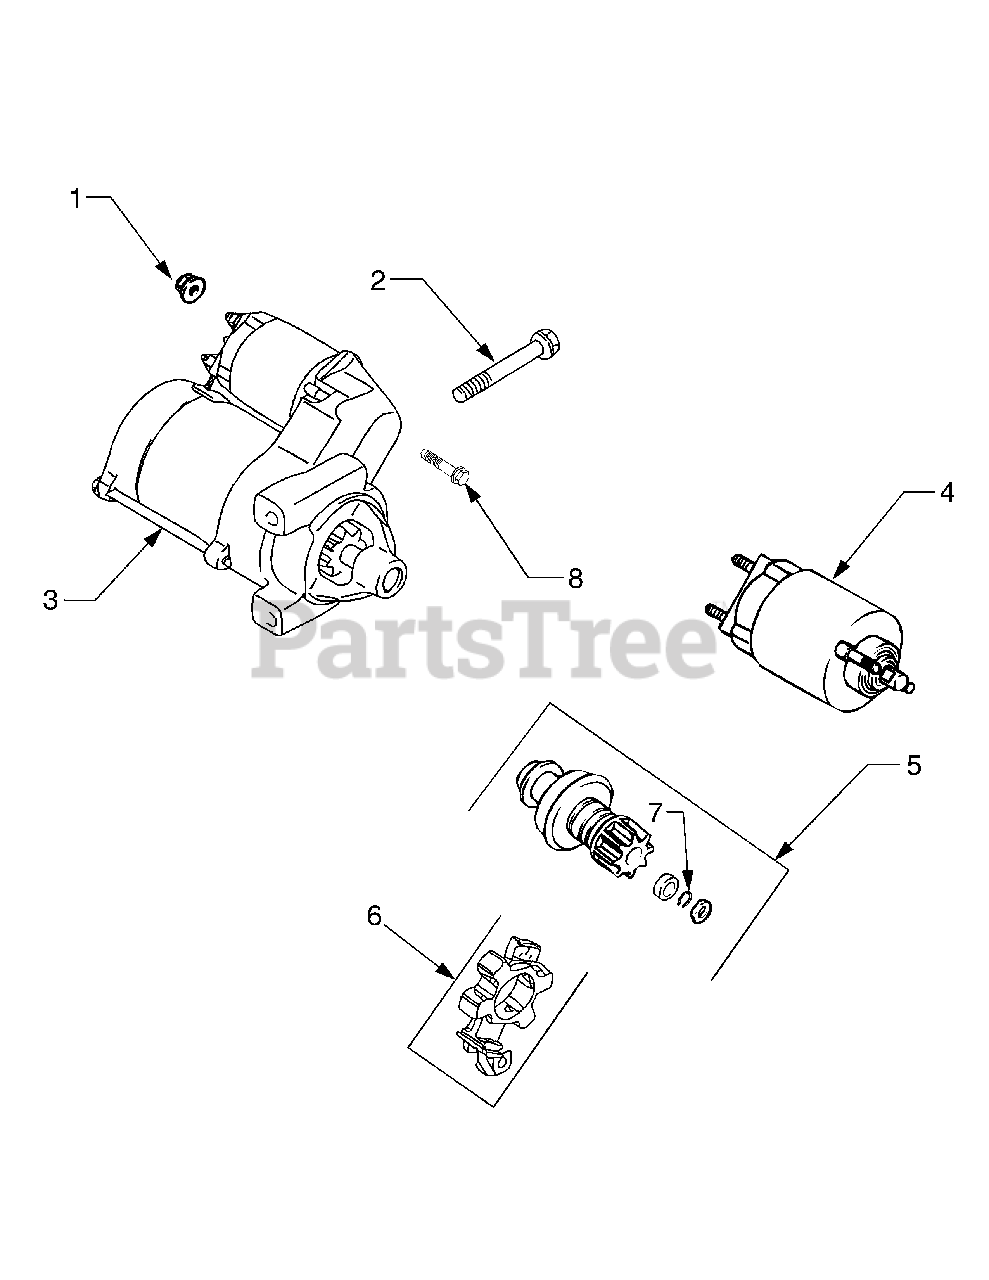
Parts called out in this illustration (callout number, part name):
1	Nut, Hex Flange M8 x 1.25"
2	Screw, Hex Flange M8 x 1.25 x 80
3	Starter, Solenoid Shift Assembly (Includes 4-8)
4	Kit, Solenoid (Includes 8)
5	Kit, Pinion Drive (Includes 7)
7	Ring, Retainer
8	Screw, External Torx Hd.
